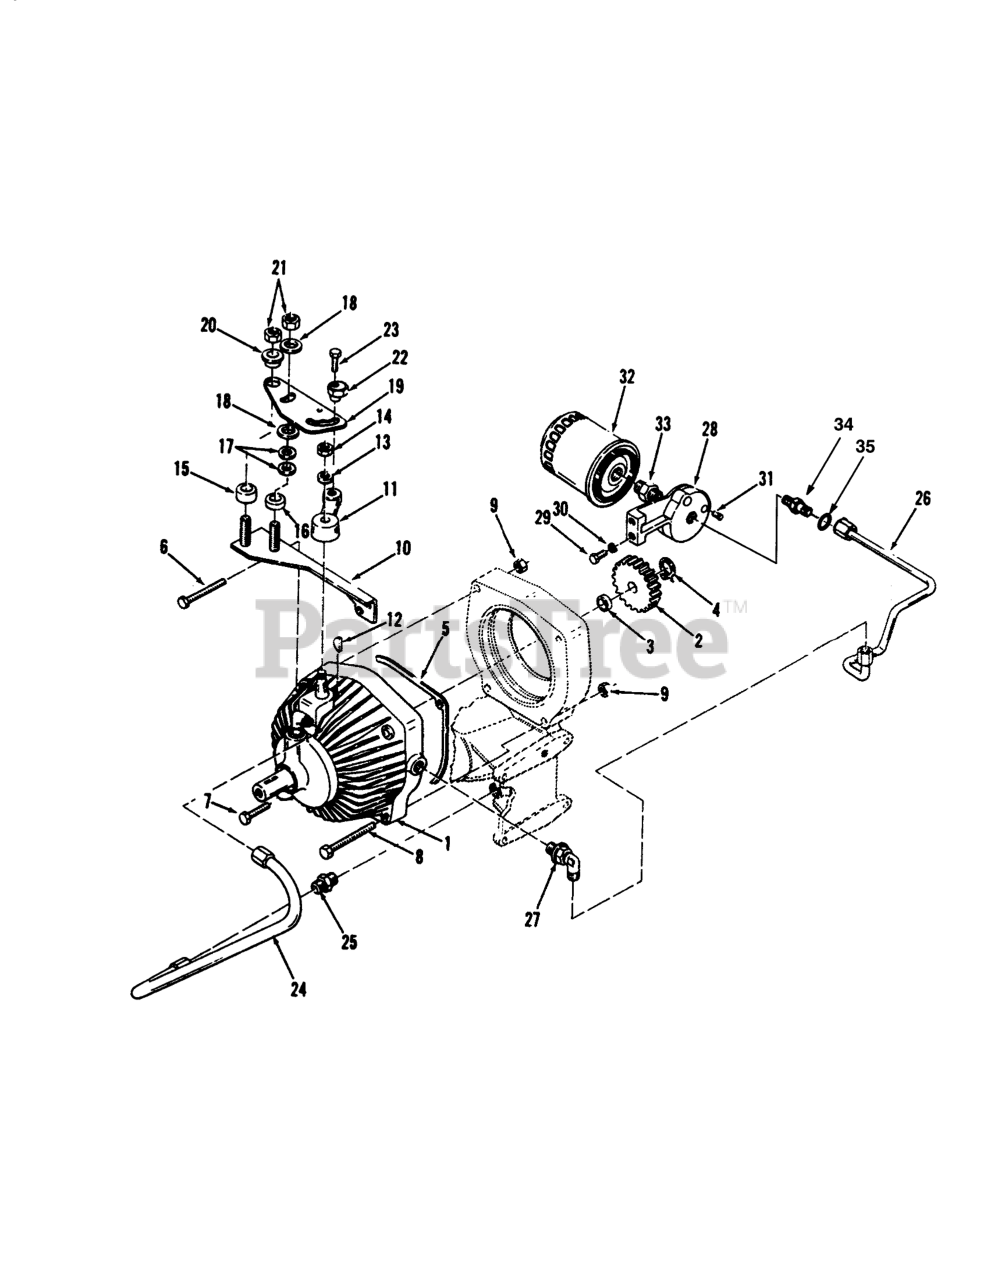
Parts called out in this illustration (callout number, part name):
1	Pump & Motor
2	GEAR 20 TEETH DRIVE
3	SPACER GEAR
4	RING-SNAP, EXTERNAL
5	GASKET
6	SCREW-HH
7	SCREW-HH
8	SCREW-HH
9	NUT-LOCK, NI
10	ASSY-PLATE B
11	ARM-SPEED CONTROLB
12	KEY-WOODRUFF
13	NUT-LOCK, NI
14	NUT-LOCK, NI
15	SPACER-PIVOT
16	SPACER-FRICTION
17	WASHER-SPRING DISC
18	FRICTION WASHER
19	CAM-SPEED CONTROL (NS)
20	CAM-SPACER
23	SCREW-HH
24	ASSY-TUBE SUCTION
25	FITTING-TUBE
26	ASS'Y-TUBE FILTER
27	ELBOW
28	BASE-FILTER
29	SCREW-HH
30	WASHER-LOCK
32	OIL FILTER ASM
33	FITTING
34	FITTING
35	0-Ring
